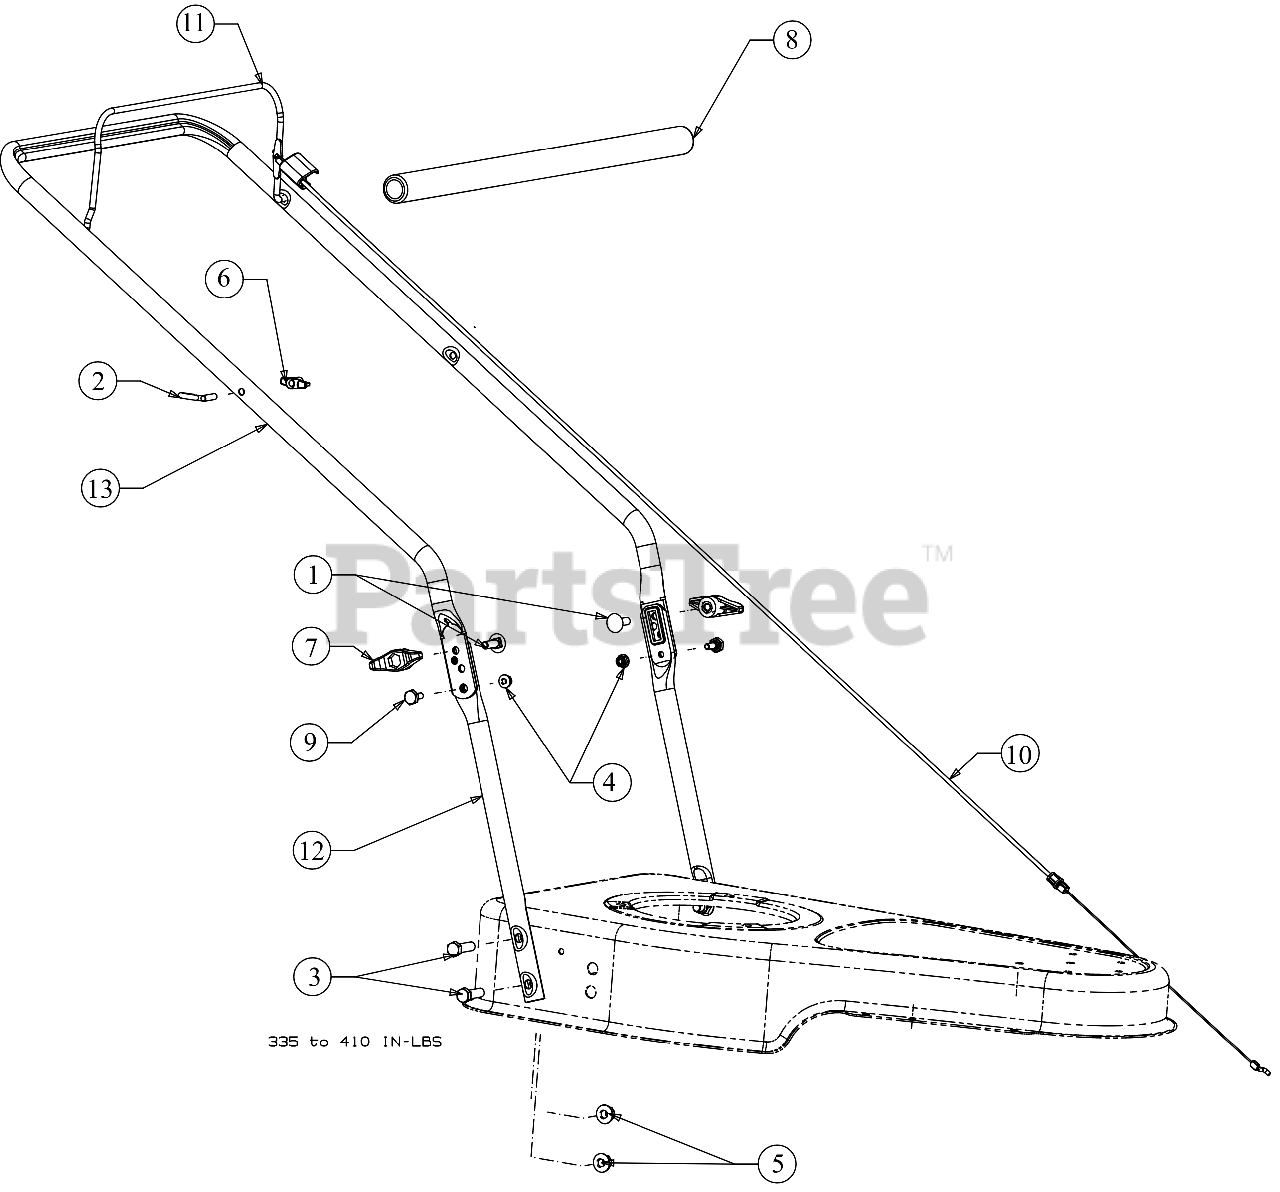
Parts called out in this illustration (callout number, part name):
1	SCREW 5/16-18 X 1.00 GR5
2	EYEBOLT 1/4-20
3	SCREW 3/8-16 X 1.25 GR5
4	FLANGE LOCK NUT
6	HANDLE KNOB
7	WING KNOB 5/16-18
8	FOAM HANDLE GRIP
9	SHOULDER SCREW
10	CONTROL CABLE 40"
11	OPERATOR BAIL
12	LOWER HANDLE (ADJUSTABLE)
13	UPPER HANDLE (ADJUSTABLE)
